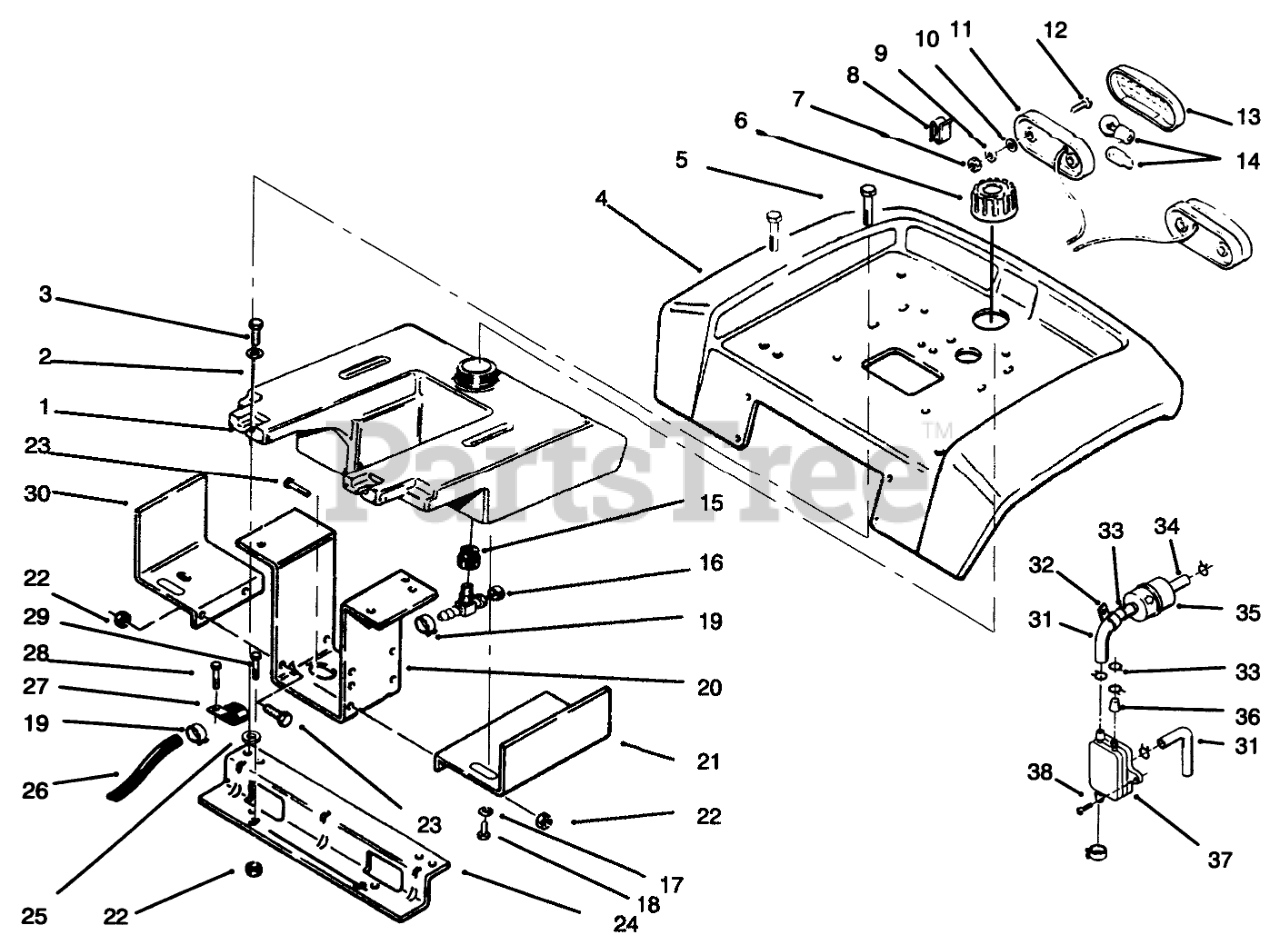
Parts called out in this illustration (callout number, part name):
1	Tank Asm-Fuel (Incl. Ref. #15- 16)
2	WASHER-FLAT
3	SCREW-HWHTF
4	Fender
6	GAS CAP ASM
7	NUT-LOCK, NI
8	SPEED CLIP
9	WASHER-FLAT
10	WASHER-LOCK, INT
11	BASE-TAIL LIGHT
12	Screw
13	LENS-TAIL LIGHT
14	Bulb
15	BUSHING
16	VALVE-FUEL
17	WASHER-LOCK
18	SCREW-HH
19	CLAMP-HOSE
20	Bracket-Fender
21	Fuel Tank Support LH
22	NUT-LOCK, NI
23	SCREW-HH
24	BRACKET-FENDER B
25	WASHER-PLAIN
26	Line-Fuel 62"
27	CLIP
28	SCREW-HH, LOCK
29	SCREW-HH
30	Support-FueITank RH
32	Clip
33	CLAMP
34	FUEL HOSE
35	FILTER-FUEL
36	CAP-FUEL OUTLET
37	PUMP-FUEL
38	Screw
